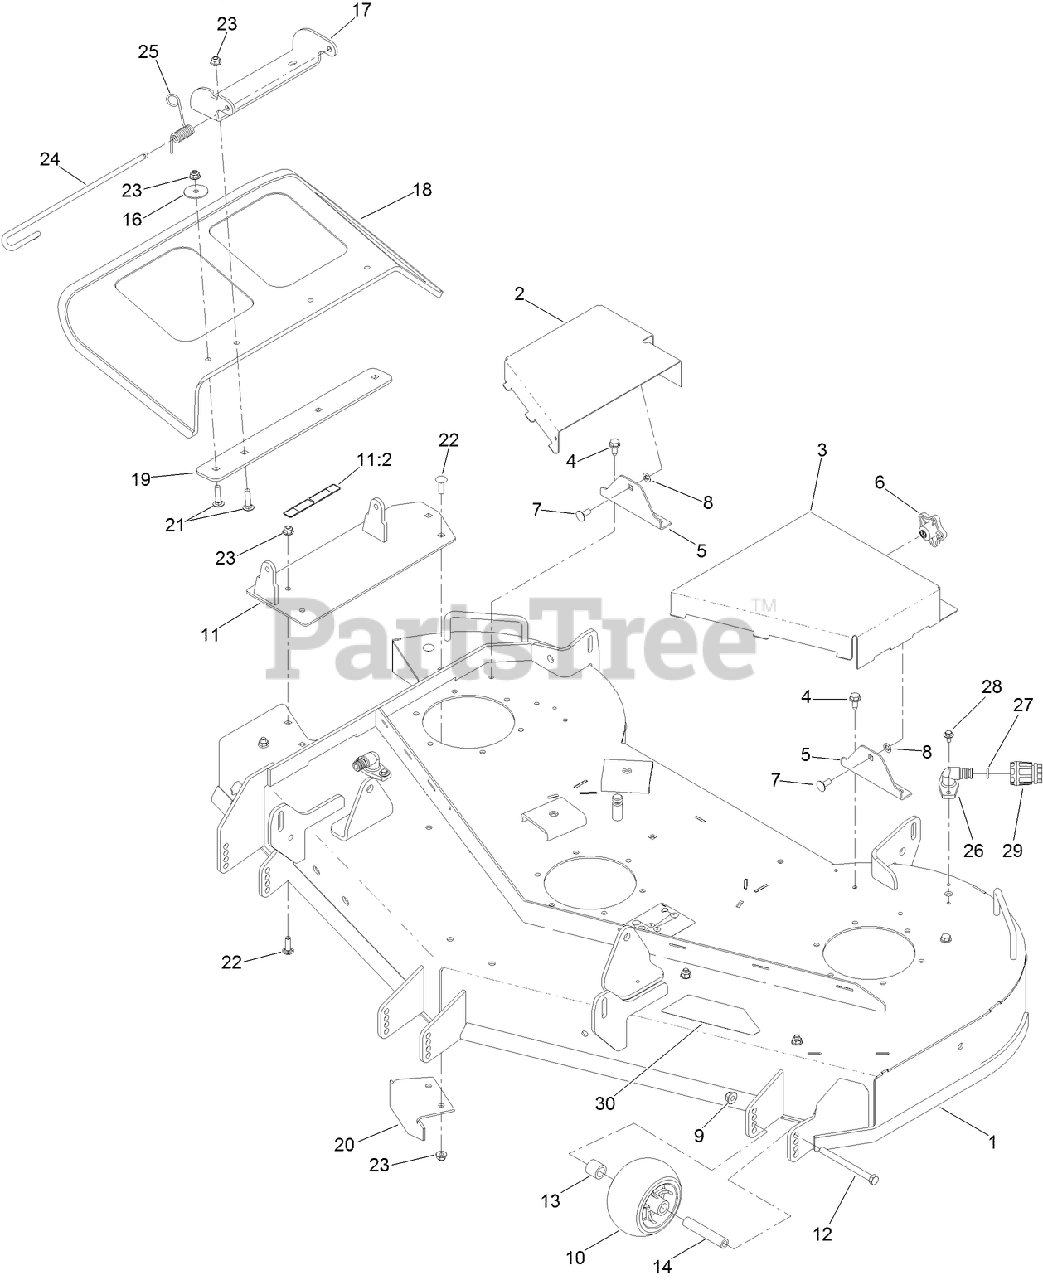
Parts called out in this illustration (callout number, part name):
1	54 INCH DECK ASM
2	COVER-BELT, RH
3	COVER-BELT, LH
4	SCREW-HWHTF
5	BRACKET-SUPPORT
6	KNOB-HANDLE
7	SCREW-CARR
8	RING-RETAINING, BOLT
9	NUT-HF, NI
10	ROLLER-SCALP, ANTI
11	PIVOT-DEFLECTOR
11:2	DECAL-DANGER
12	SCREW-HH
13	SPACER-AXLE, REAR
14	TUBE-SPANNER
16	WASHER-FLAT
17	BRACKET-DEFLECTOR, UPPER
18	DEFLECTOR
19	PLATE-DEFLECTOR
20	BAFFLE-CUTOFF
21	SCREW-CARR
22	SCREW-CARR
23	NUT-HF, NI
24	PIN-CHUTE
25	SPRING-TORSION
27	O-RING
28	SCREW-HHFTF
29	CONNECTOR-HOSE
